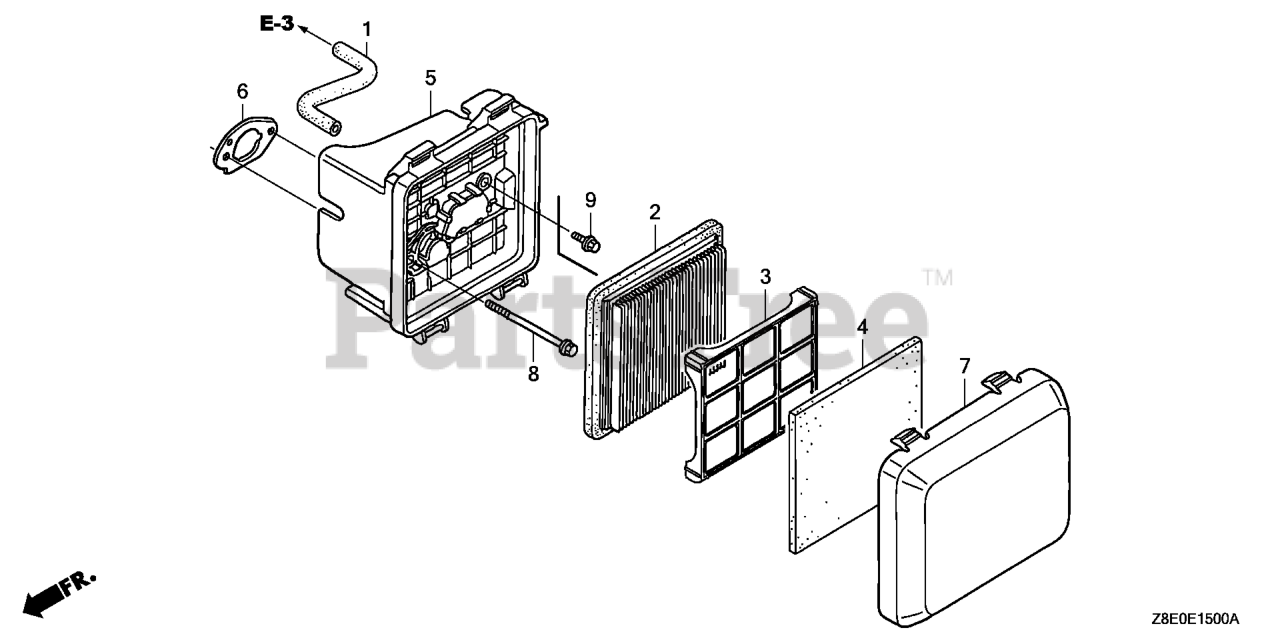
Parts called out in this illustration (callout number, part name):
1	TUBE, BREATHER
2	ELEMENT, AIR CLEANER (TOYO ROKI) (ENGINE NO.)
3	GRID, AIR CLEANER
4	FILTER (OUTER) (WET)
5	CASE ASSY., AIR CLEANER
6	GASKET, AIR CLEANER
7	COVER, AIR CLEANER (DUAL)
8	BOLT, SPECIAL (6MM)
